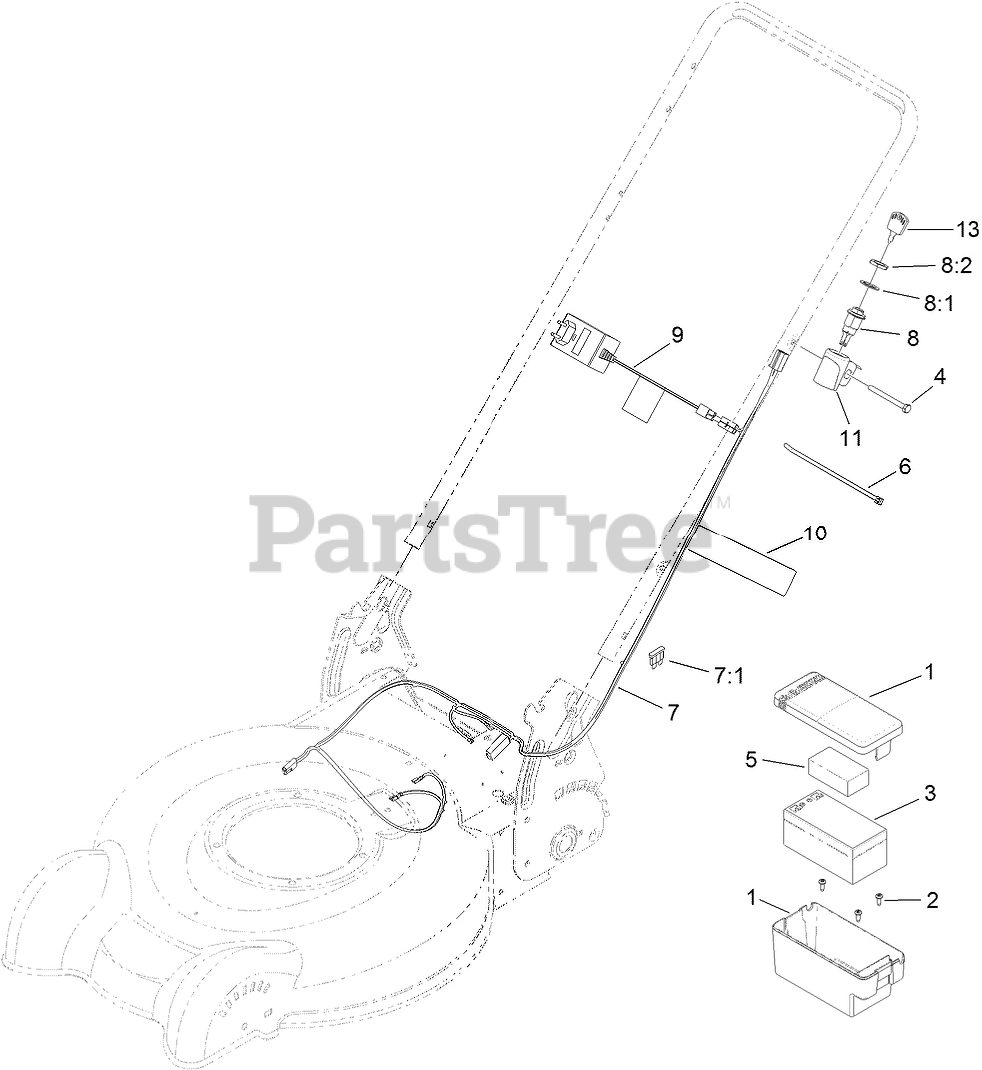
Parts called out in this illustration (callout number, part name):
1	BATTERY BOX ASM
2	SCREW-FORMING, THREAD
3	BATTERY-WET
4	SCREW-HH
5	FOAM-BATTERY, TOP
6	TIE-CABLE
7	HARNESS-WIRE
7:1	FUSE-40 AMP
8	STARTER SWITCH ASM
8:1	WASHER-TOOTH, INTERNAL
8:2	NUT-HH
9	CHARGER-BATTERY
10	DECAL-WARNING
11	MOUNT-SWITCH
